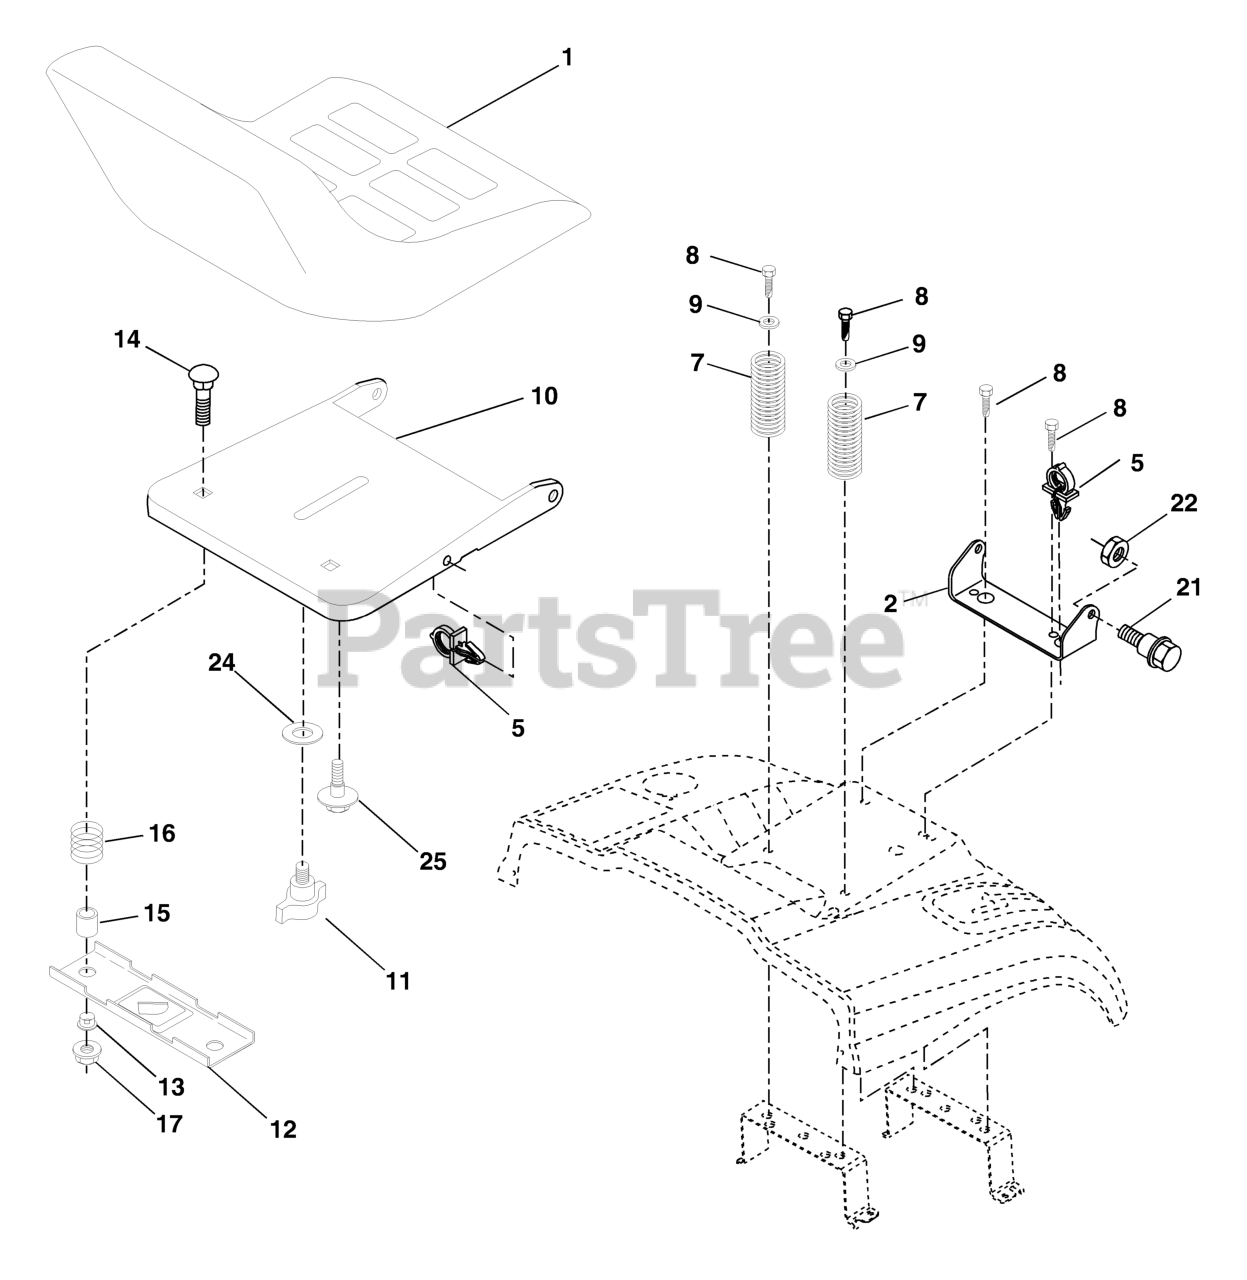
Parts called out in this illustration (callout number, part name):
1	SEAT, GRAY
2	SEAT PIVOT BRKT
7	SPRING COMPRESSION
8	SCREW THDROL 3/8-16 X 1-1/2
9	WASHER
10	PAN, SEAT
11	KNOB.SEAT.ADJ.WINGNUT
12	BRKT SWITCH
14	BOLT.ROUND.HEAD.SQUARE.NECK
15	SPACER SPLIT 28X.96
17	NUT T
21	BOLT SHOULDER 5/16-18
22	NUT.71038.31-18.HEX.NYLOCK
24	WASHER GT
25	BOLT,SHOULD
